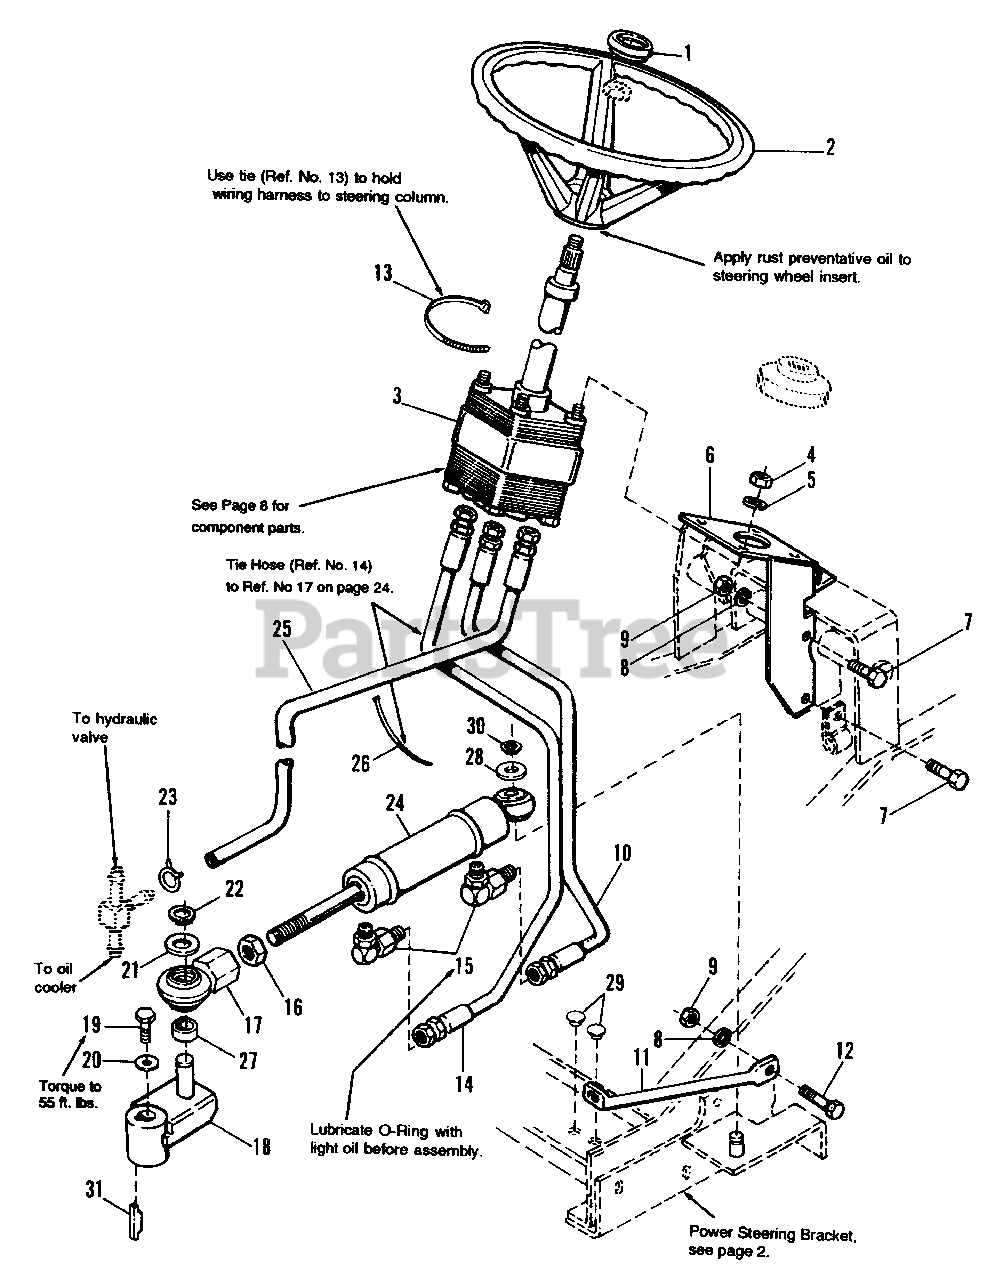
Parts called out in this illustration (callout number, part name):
1	CAP, Steering Wheel
2	WHEEL ASSY., Steering
3	STEERING UNIT, Hydrostatic (See pages 6 & 7 for components.)
4	NUT, Hex, 5/16-24
5	LOCKWASHER, 5/16
6	SUPPORT ASSY., Steering Valve
7	CAPSCREW, Hex Hd., 3/8-16 x 1, Gr. 5
8	LOCKWASHER, 3/8
9	NUT, Hex, 3/8-16
10	HOSE ASSY., Hyd. (Valve to Cyl.)
11	BRACE, Cylinder
12	CAPSCREW, Hex Hd., 3/8-16 x 1-1/2, Gr. 5
14	HOSE ASSY., Hyd. (Valve to Cyl.)
15	FITTING, Hyd., 9/16-18 x 9/16-18-90 degree
16	NUT, Hex, 3/4-16
17	BALL JOINT ASSY.
18	ARM ASSY., Steering
19	CAPSCREW, Hex Hd., 3/8-16 x 7/8, Gr.8
20	WASHER, Spring
21	WASHER
22	RING, Retaining, 3/4
23	HOSE CLAMP
24	CYLINDER, Power Steering
25	HOSE ASSY., Hyd., (Valve to Cooler)
26	TIE, Self-Locking
27	SPACER
29	PLUG, Plastic
30	RING, Retaining, 5/8
31	KEY, Hi-Pro, 1/4 x 3/4
31	ROD SEAL KIT, (for Power Steering Cylinder)
